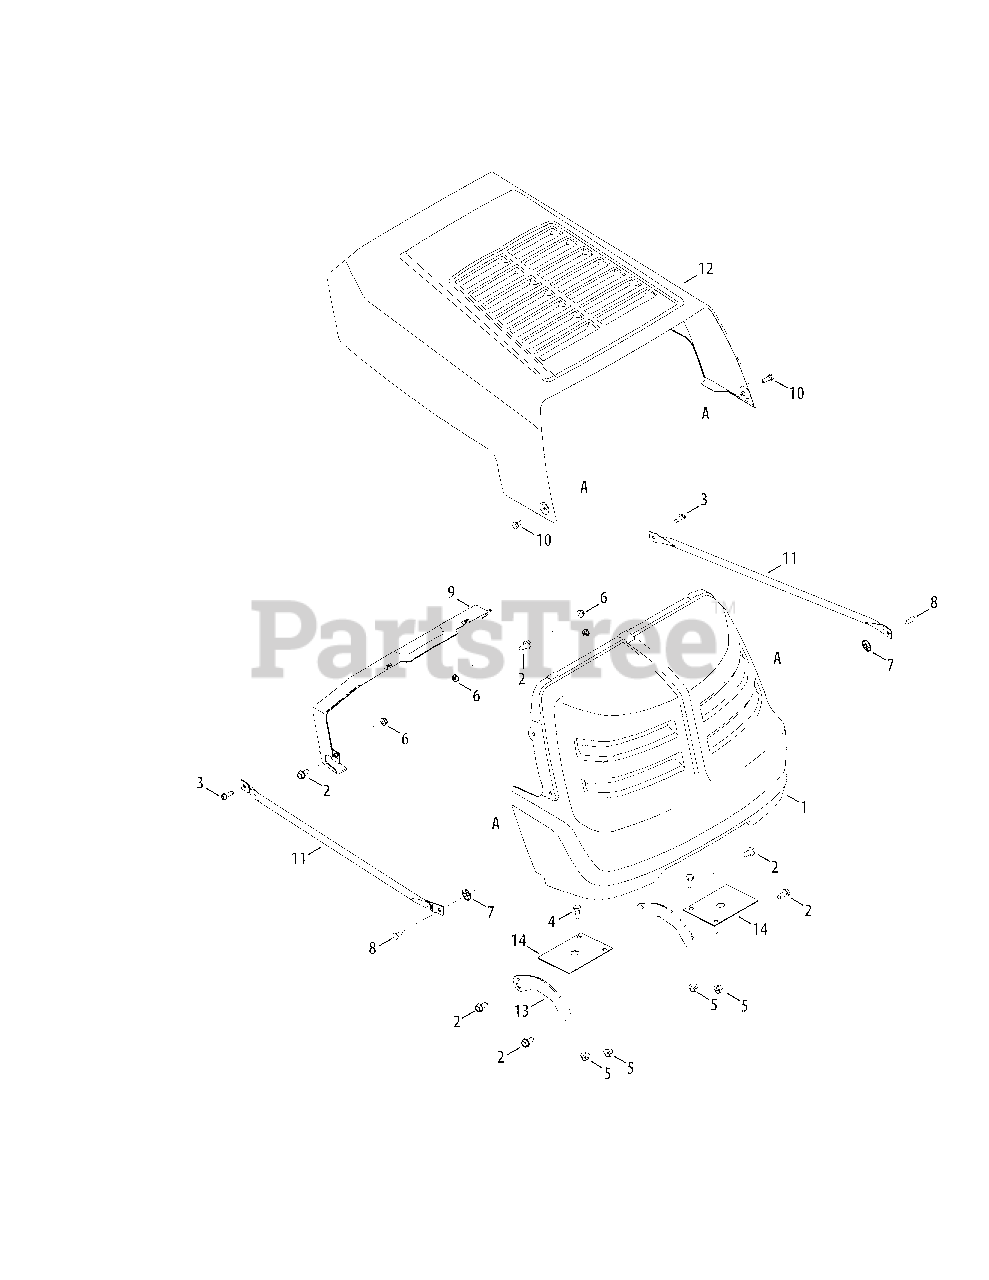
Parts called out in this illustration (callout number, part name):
1	Grill Assembly
2	Screw, Tap, 5/16-18x .750
3	Screw, Tap, 1/4-20x 0.750
4	Hex Screw, 5/16-18x .75
5	Flange Lock Nut, 5/16-18
6	Flange Lock Nut, 1/4-20
7	Nut, push-On, .25 Dia
8	Rivet, flat Head 1/4"
9	Collar, dash
10	Bolt, Shoulder, .375 X .125
11	Grill Support Rod
13	Front Pivot Support Bracket
14	Support Bracket
